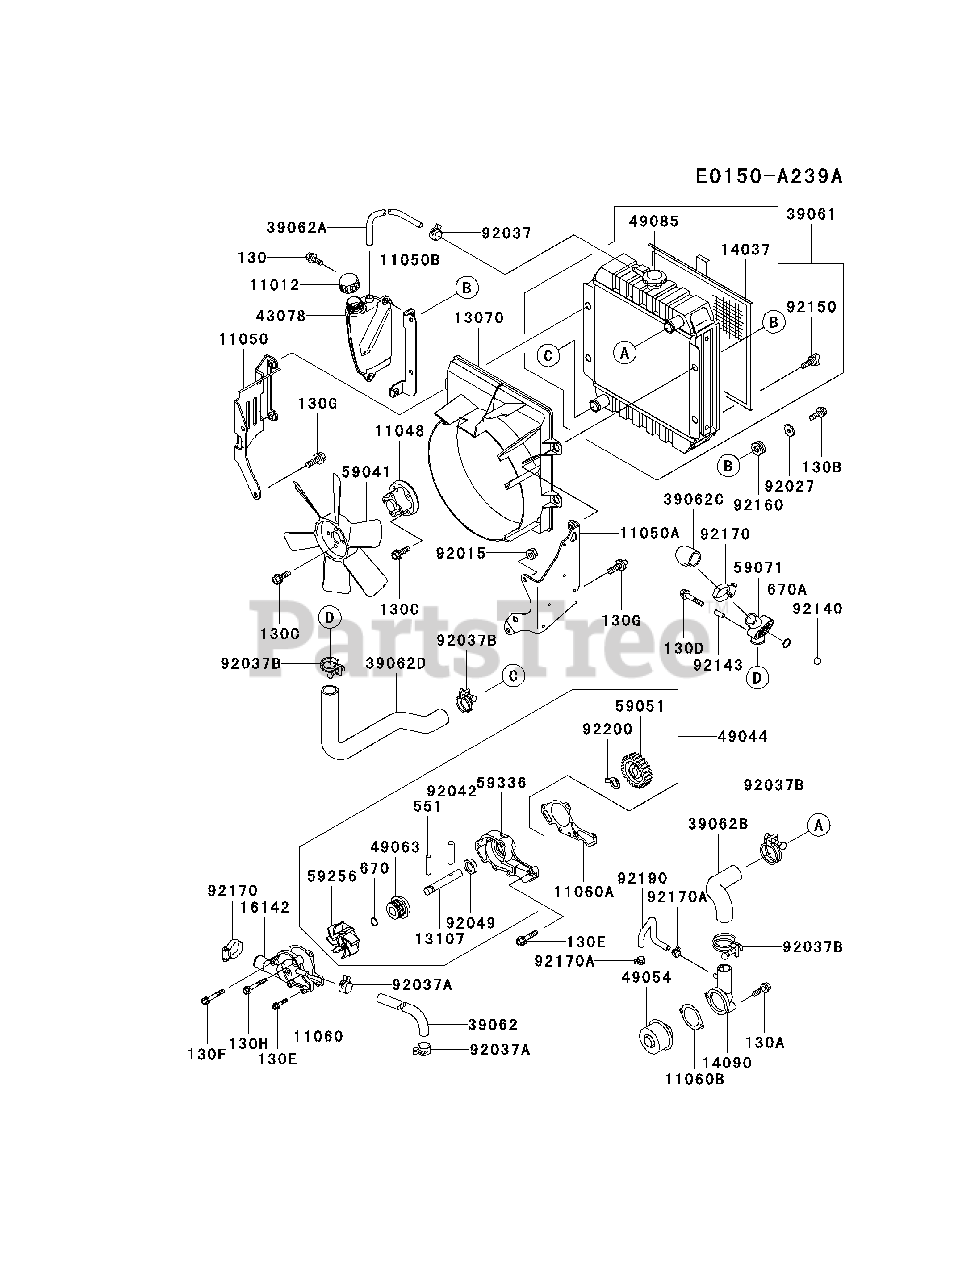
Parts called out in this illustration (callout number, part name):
130	BOLT-FLANGED
130A	BOLT-FLANGED
130B	BOLT-FLANGED
130C	BOLT-FLANGED
130D	BOLT-FLANGED
130E	BOLT-FLANGED
130F	BOLT-FLANGED
130G	BOLT-FLANGED
130H	BOLT-FLANGED
551	PIN-DOWEL
670	O RING
670A	O RING
92170	CLAMP
